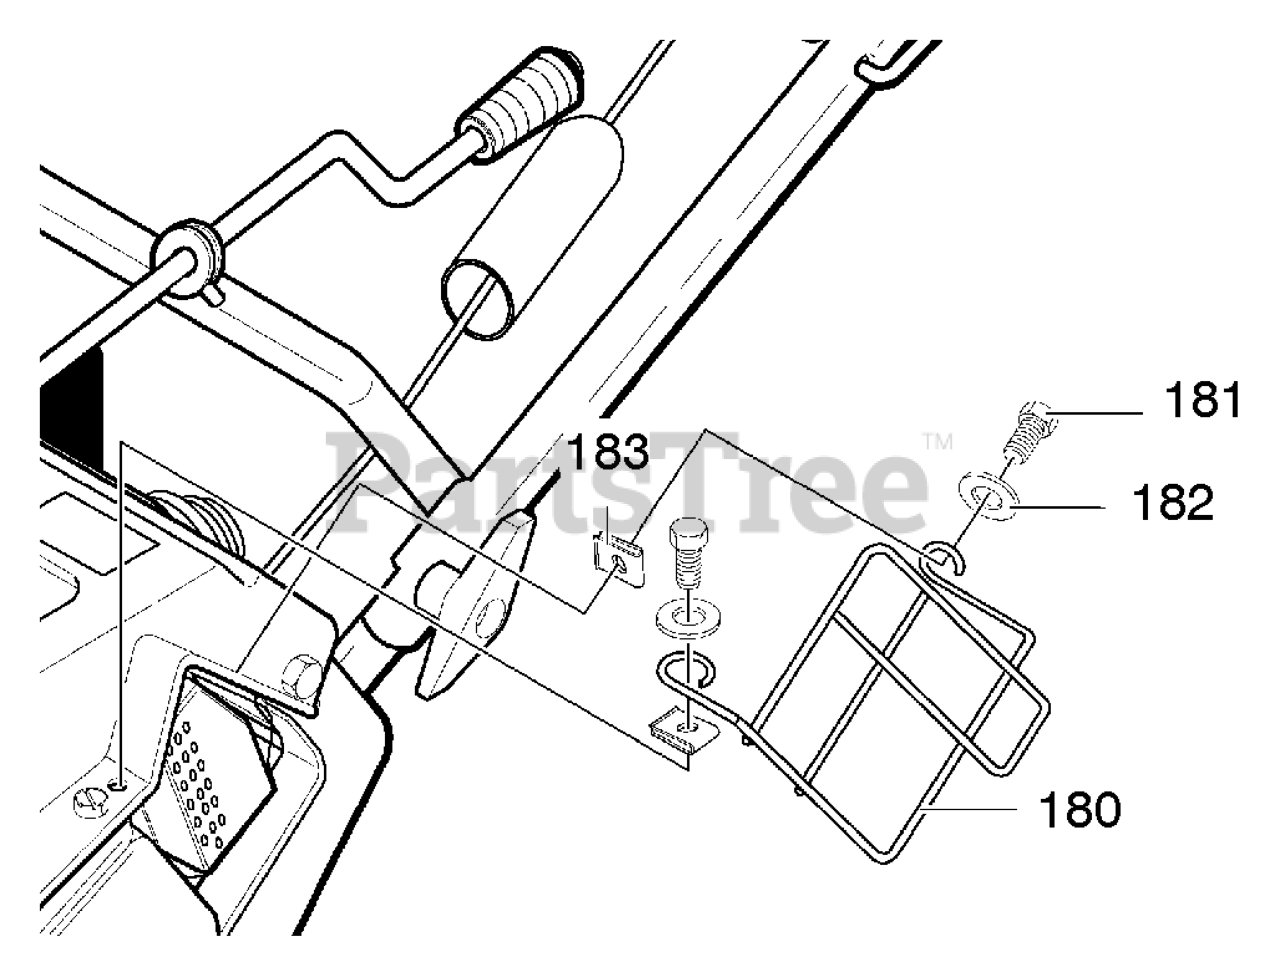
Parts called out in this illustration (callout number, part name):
180	GUARD, MUFFLER -EXPT
181	SCREW
182	WASHER, FLAT
183	NUT, 1/4-20 TINN
